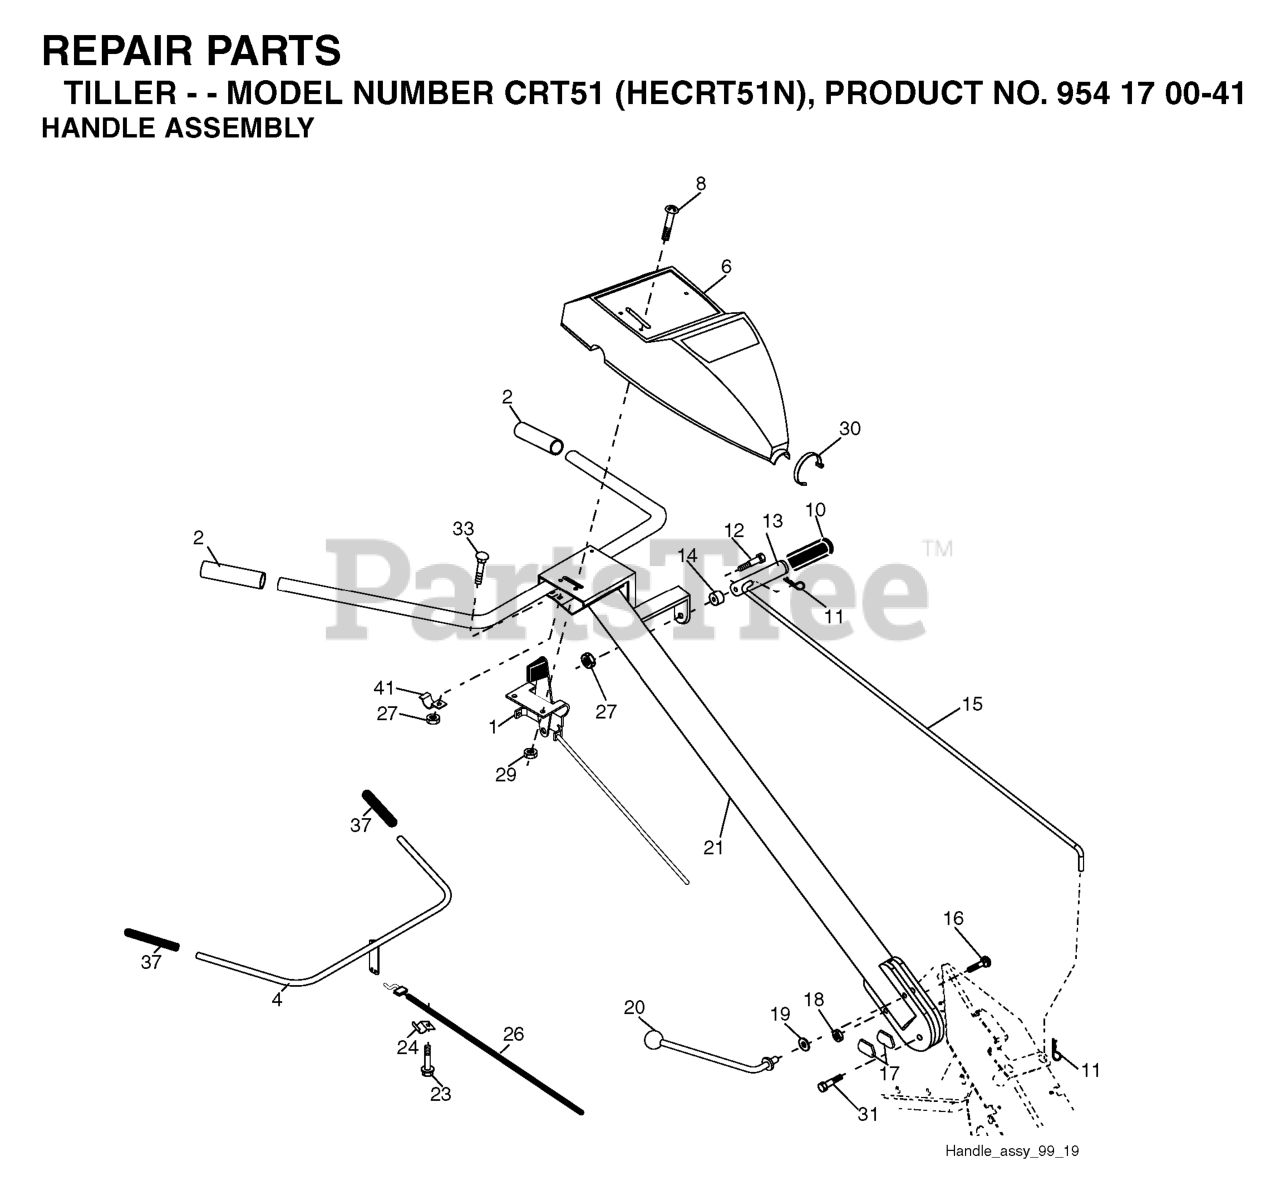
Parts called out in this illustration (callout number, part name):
1	THROTTLE.CONTROL.CRT.TILLER
2	KIT.GRIP.HANDLE.5.00.BLK.VINYL
4	CONTROL BAR ASSY
6	RP CONTROL PANEL
8	SCREW.PNHD.10-24
10	GRIP T
11	RETAINER M
12	SHOULDER BOLT ST
13	HANDLE.SHIFT.TILLER
14	GROMMET.RUBBER.CRT.TILLER
15	SHIFT ROD CRT
16	BOLT D
17	LOCK.HANDLE.CRT
19	WASHER CRT
20	LEVER.LOCK.CRT
21	REPL BY 532 1805-17
23	TAPPING SCREW
24	CONDUIT.CLIP.PLATED
26	CABLE.CLUTCH
27	NUT T
29	NUT **
30	TIE CABLE CRT
31	BOLT.PIVOT
37	GRIP BAR CRT(1)
41	CLAMP.BAR.CRT.BLACK
